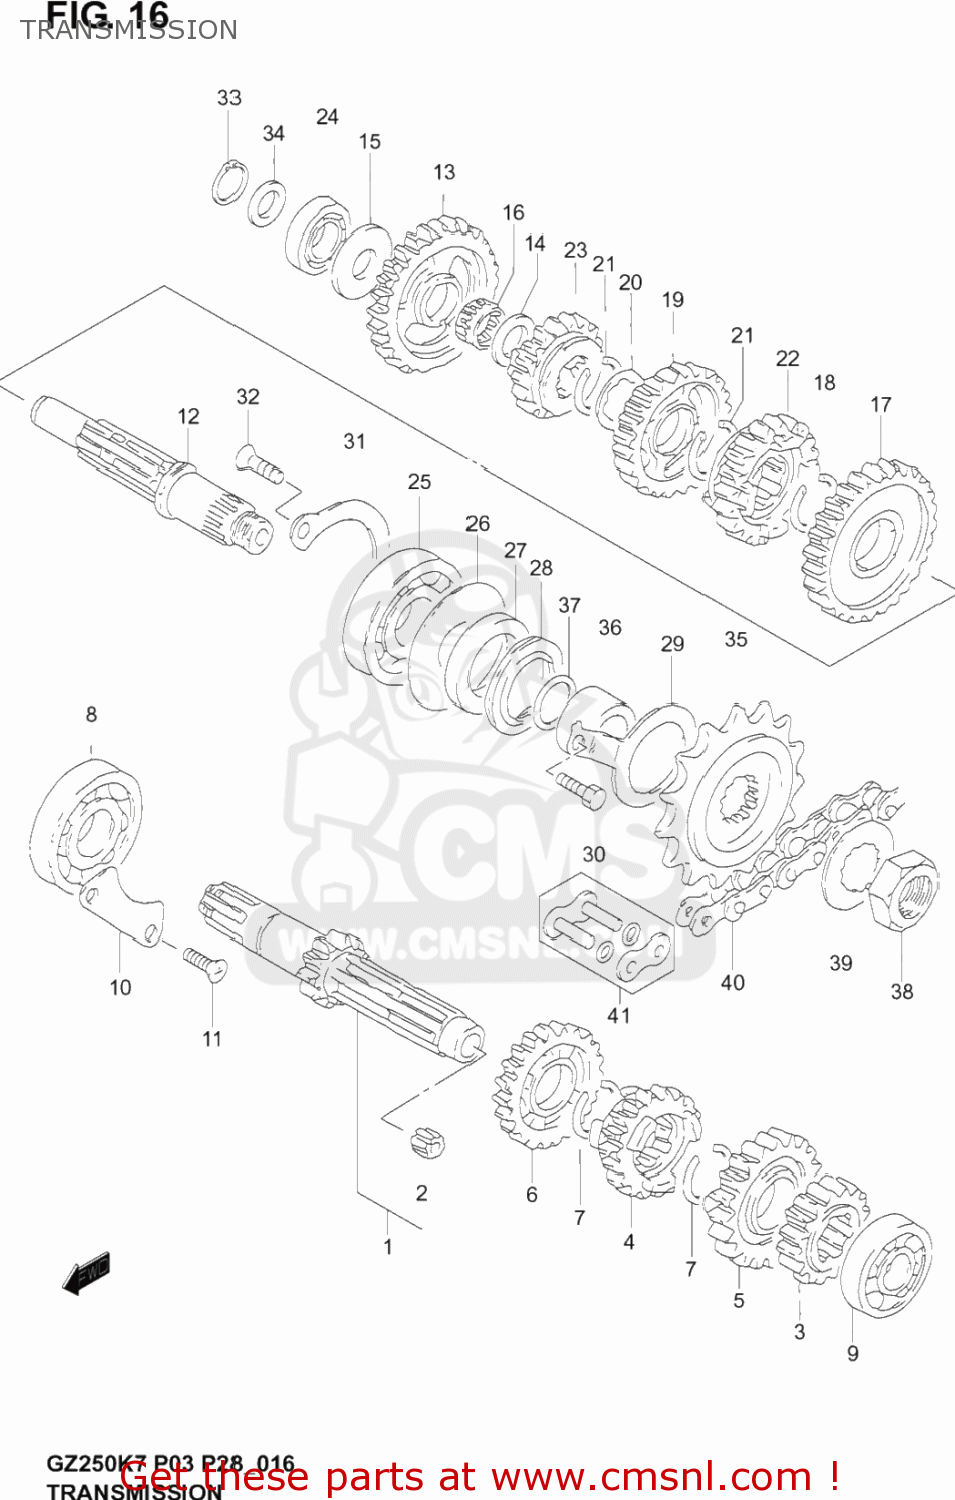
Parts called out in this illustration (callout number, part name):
1	SHAFT,COUNTER(NT:11)
2	BUSH
3	GEAR,2ND DRIVE(NT:16)
4	GEAR,3RD DRIVE(NT:19)
5	GEAR,4TH DRIVE(NT:20)
6	GEAR,5TH DRIVE(NT:22)
7	CIRCLIP
8	BEARING(22X56X16)
9	BEARING(17X40X12)
10	RETAINER,CNTR SHAFT BEARING
11	BOLT(6X12)
12	SHAFT,DRIVE
13	GEAR,1ST DRIVEN(NT:29)
14	SHIM(17X28X1)
15	WASHER
16	BEARING(17X21X9.8)
17	GEAR,2ND DRIVEN(NT:27)
18	CIRCLIP
19	GEAR,3RD DRIVEN(NT:24)
20	WASHER,LOCK
21	CIRCLIP
22	GEAR,4TH DRIVEN(NT:20)
23	GEAR,5TH DRIVEN(NT:18)
24	BEARING(17X36X12)
25	BEARING(22X56X16)
26	WASHER(35X55X1)
27	OIL SEAL (30X43X5)
28	SEAL,OIL(30X43X7)
29	RETAINER,DRIVE SHAFT OIL SEAL
30	BOLT
31	RETAINER,DRIVE SHAFT BEARING
32	SCREW
33	CIRCLIP,17MM
34	SHIM(17X24X1)
35	SPROCKET, ENGINE (NT:15)
36	SPACER
37	O RING(D:2.5,ID:21)
38	NUT
39	WASHER,LOCK
40	CHAIN ASSY (DID520VC5, 110LE)
41	JOINT SET OPT
